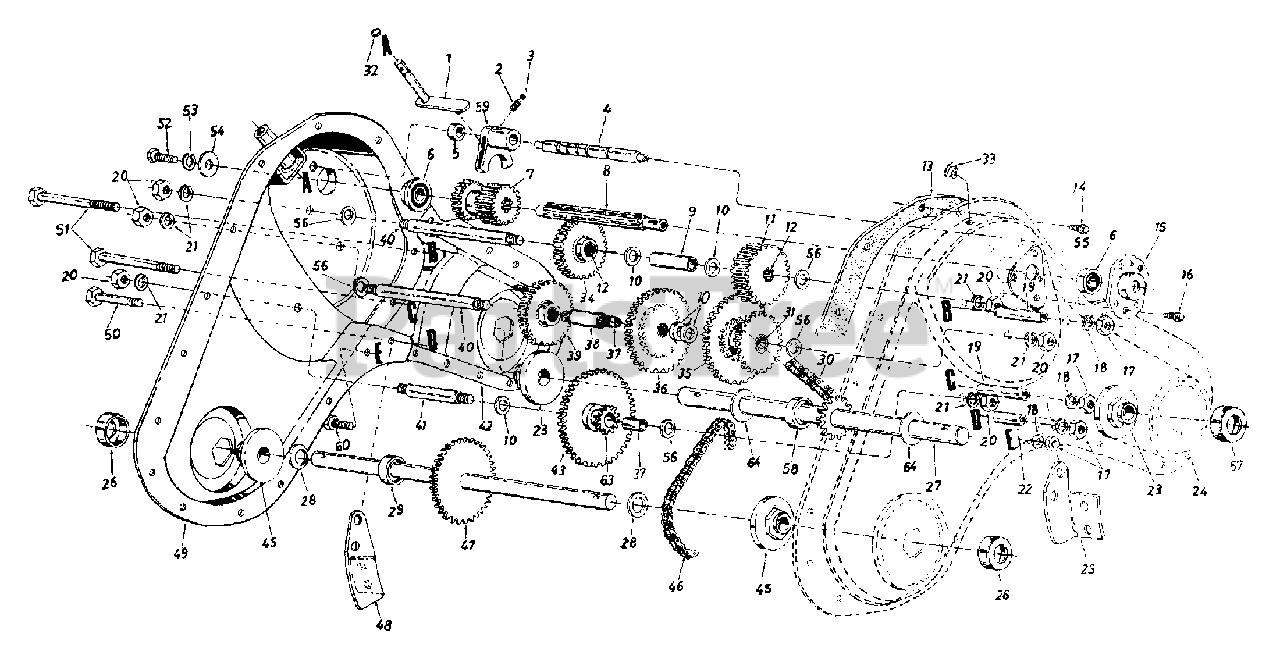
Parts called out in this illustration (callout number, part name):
1	Shifting Bracket Ass'y.
2	Compression Spring .50" Lg.
3	Ball Detent .250" Dia.
4	Detent Shaft 1/2" Dia.
5	Spacer .505" I.D. x .88" O.D.
6	Ball Brg. .62" I.D. x 1.38"
7	Spur Gear 16T (Input)
8	Input Spline Shaft 7/8"
9	Spacer .657" I.D. x 2.85" Lg.
10	Fl-Wash. .640" I.D. x 1.24"
11	Spur Gear 30T 7/8" I.D.
12	Needle Bearing 5/8" I.D.
13	Gasket - Trans. Hsg.
14	Hex S-Tap Scr. 1/4-20 x .5"
15	1-3/8" Dia. Bearing Housing
16	Hex TT-Tap Scr. 1/4-20 x .75"
17	Hex Nut 5/16-18 Thd.
18	L-Wash. 5/16" I.D.
19	Spacer 1.56" Lg.
20	Hex Nut 7/16-20 Thd.
21	Bell-Wash. .45" I.D. x 1.0"
22	Spacer 1.015" Lg.
23	Tine Shaft Brg. 1.002 x 2.50
24	Trans. Housing Ass'y. - L.H.
27	Tine Shaft Ass'y. 1" O.D.
28	Fl-Wash. .76" I.D. x 1.5" O.D.
29	Spacer .75" I.D. x .50" Lg.
30	Chain #50 5/8 Pitch x 52 Links - Endless
31	Needle Bearing 5/8" I.D.
32	Snap Ring
33	Taper Cap Plug
34	Spur Gear 30T 12/16" I.D.
35	30/44T Gear Ass'y. Comp.
36	Spur Gear 44T
37	Sleeve Bearing
38	Gear Hub 3/4" I.D. x 3" Lg.
39	Spur Gear 30T 1.0" I.D. x 1/2" W
40	Jack Shaft 5/8" Dia. x 5"
41	Jack Shaft 5/8" Dia. x 2.38"
45	Wheel Brg. .752" x 2.5"
46	#420 Chain 1/2 Pitch x 50 Links - Endless
47	Wheel Shaft Ass'y. 15.6"
51	Hex Bolt 5/16-18 x 2.5"
52	Hex Bolt 1/4-20 x .62" Lg.
53	L-Wash. 3/8" I.D.
54	Fl-Wash. 1/4" I.D. x .93" O.D.
55	Gear Positioner Bracket
56	Fl-Wash. 7/16" I.D. x 1-3/8"
57	Dust Cover Ass'y. 1" Shaft
58	Spacer 1" I.D. x 2" O.D.
59	Shifting Fork
60	Hex Bolt 5/16-18 x .75" Lg.
63	10T Sprocket Ass'y.
64	Thrust Wash. 1.03" I.D. x 1.62" O.D.
